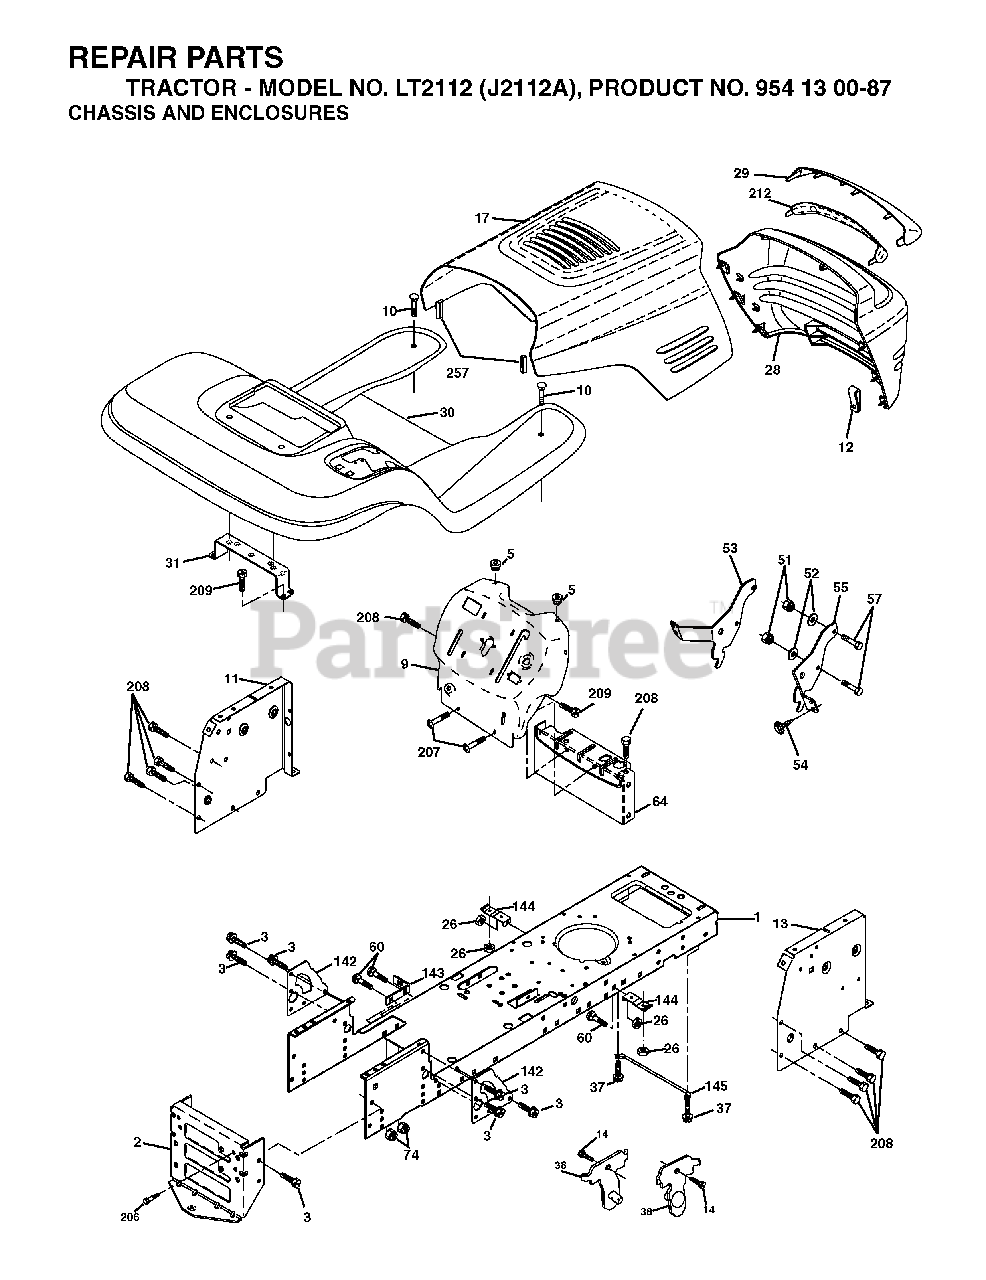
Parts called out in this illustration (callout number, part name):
1	CHASSIS STAMPING
2	DRAWBAR, 12GA
3	SCREW 3/8-16X3/4
5	BUMPER.RUBBER.HOOD
10	BOLT D
11	PANEL.DASH.LH.LTX
13	PANEL DASH RH
14	SCREW LT
26	NUT
37	SCREW LT
38	BRACKET.ASM.PIVOT.MOWER.REAR
51	LOCKNUT
52	WASHER
57	BOLT
64	DASH LOWER
74	LOCKNUT
142	PLATE REINFORCEMENT
143	BRACKET, SWAY BAR
144	BRKT, FOOT REST
145	ROD PIVOT CHASSIS/HOOD
206	SHOULDER BOLT 5/16-18TT
207	SCREW, 5/16-18 X 1/2
208	SCREW 3/8-16X1/2
209	SCREW, 3/8-16X3/4
257	BUMPER.HOOD.LARGE.1.75"
